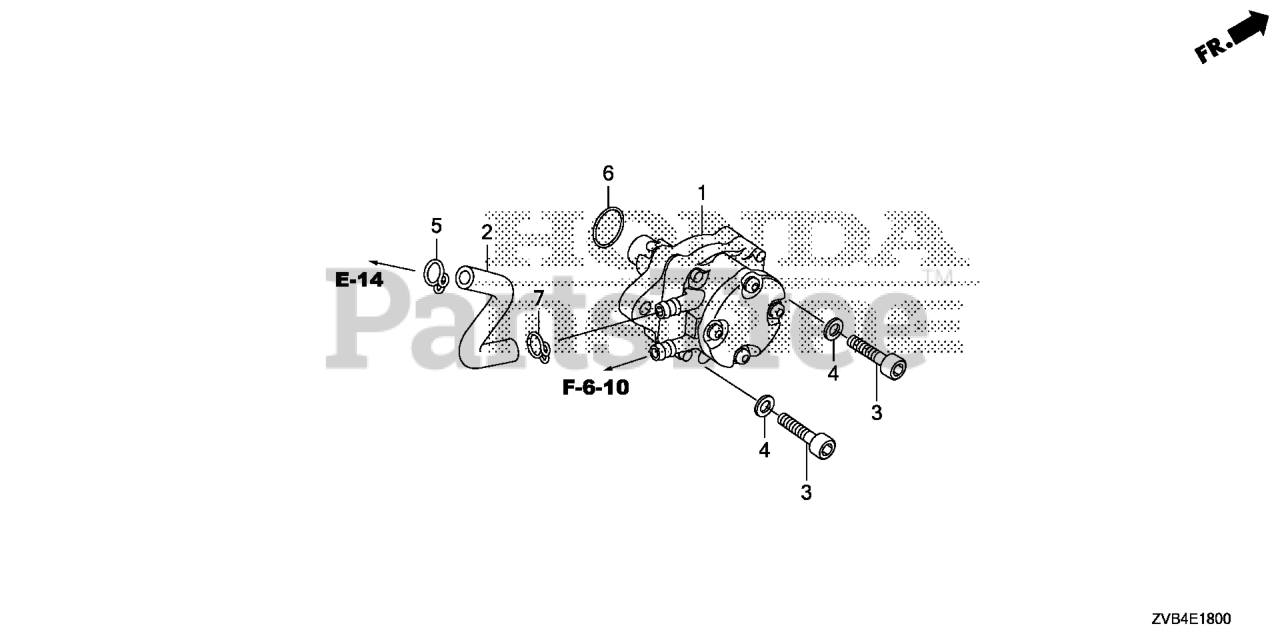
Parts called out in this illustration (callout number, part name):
1	PUMP ASSY., FUEL (MSDS)
2	TUBE E, FUEL
3	BOLT, SOCKET (6X22)
4	WASHER, PLAIN (6MM)
5	CLIP, TUBE (B1 9)
6	O-RING (20.8X2.4)
7	CLIP, TUBE (B1 8)
